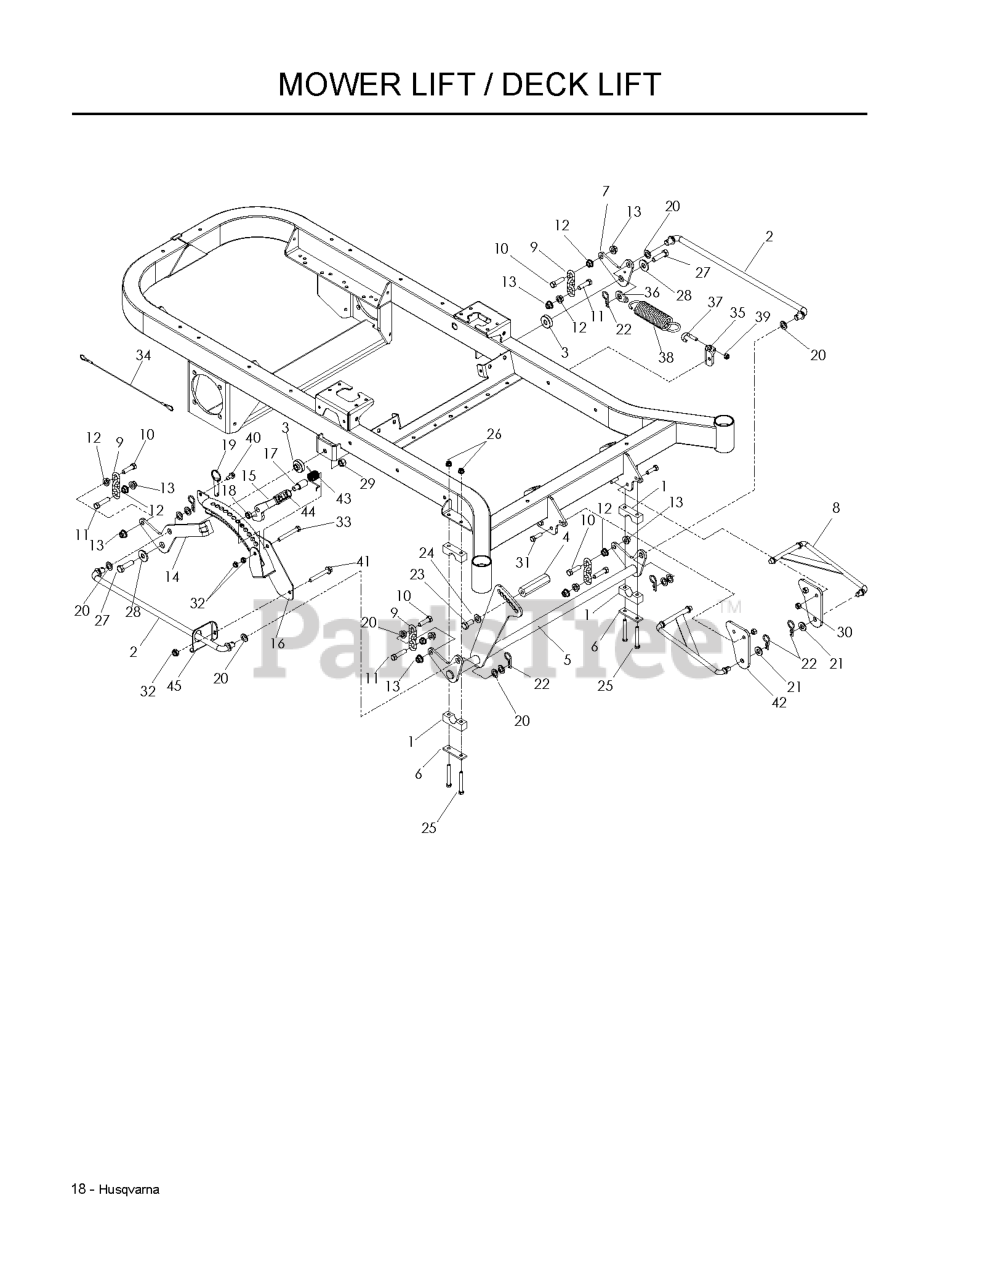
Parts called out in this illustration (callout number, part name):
1	PILLOW BLOCK
2	CROSS LINK
3	IDLER SPACER
4	PEDAL, FOOT, HEX
5	SHAFT, FRONT-LIFT
6	REINFORCEMENT BAR
7	BELLCRANK, RR, LIFT
8	STRUT LINKAGE
9	LIFT CHAIN - 3 LINK
10	HCS 7/16C X 1 1/2
11	HCS 7/16 - 14 X 1 3/4
12	NUT 7/16C WHIZ
13	NUT 7/16-14 HEX WHIZ LK
14	BELLCRANK, RR, RT
15	LATCH, TRANSPORT
16	HEIGHT, ADJUST, DECK
17	PIVOT, LATCH, TRANSPORT
18	SPACER, .3
19	PIN, 1/2 X 1 1/2, DETENT RING
21	WASHER 1/2" FLAT
22	PIN, COTTER 1 3/4
23	HHCS 1/2-13 X 1
24	WASHER, 7/16 DISC SPRING
25	HCS 5/16C X 2-3/4
26	5/16-18 NYLOC FLANGE NUT
27	HCS 1/2-13 X 1 3/4 GR 8
28	WASH USS FLAT 1/2
29	NUT 1/2-13 HEX NYLOC ZD
30	NUT 3/8-16 NYLOC
31	HCS 3/8C X 1 1/4 GR5
32	NUT HEX 3/8-16 NYLON, THIN
33	HCS 3/8C X 3
35	MOUNT, SPRING
36	TAB, SPRING
39	NUT 5/16 NYLOC
40	BOLT 5/16-18 X 3/4
41	HHFS 3/8-16 X 2 3/4
42	MOUNT, STRUT
43	SPRING, TORSION
44	GRIP, TRANSPORT-RELEASE
